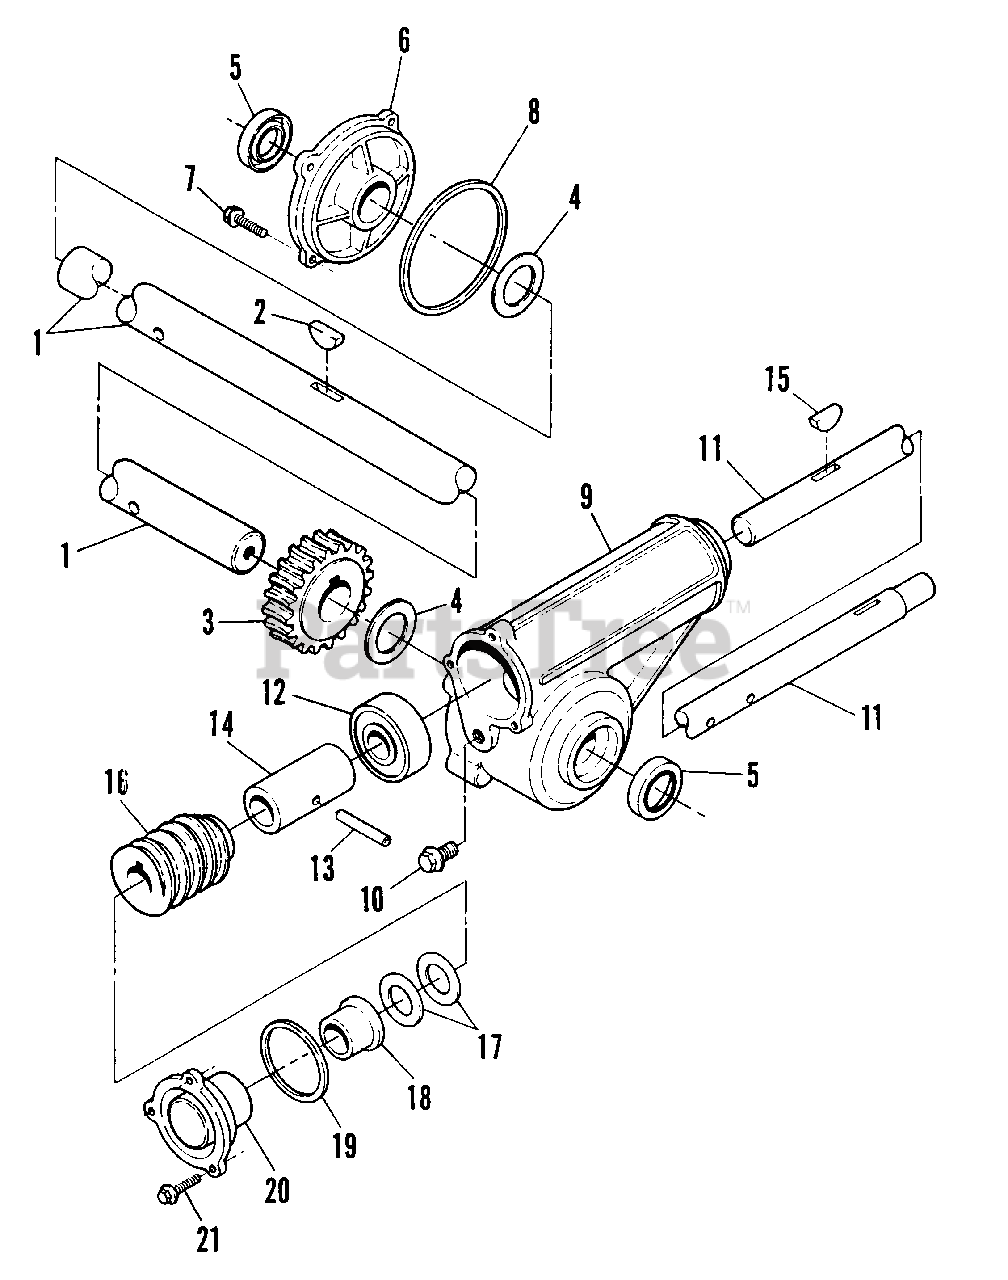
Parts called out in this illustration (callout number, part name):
1	SHAFT, Auger
2	KEY, 1/4 x 7/8" Woodruff
3	GEAR, Worm
4	WASHER, 1.0 x 1-1/2" Thrust
5	SEAL, Oil
6	COVER, Gear Case
7	SCREW, 1/4-20 x 3/4" Self-Tapping
8	O-RING, Case Cover
9	CASE, Gear
10	SCREW, 3/8-16 x 1/2" Self-tapping
11	SHAFT, Impeller
12	BEARING, Impeller Shaft
13	PIN, 1/4 x 1-1/2" Roll
14	SPACER, Gear Bearing
15	KEY, 3/16 x 7/8" Woodruff
16	GEAR, Rolled Worm
17	WASHER, 3/4 x 1-1/8" Thrust
18	BUSHING, Impeller Shaft
19	O-RING, Case Cap
20	CAP, Case
21	SCREW, #10-24 x 5/8" Self-Tapping
